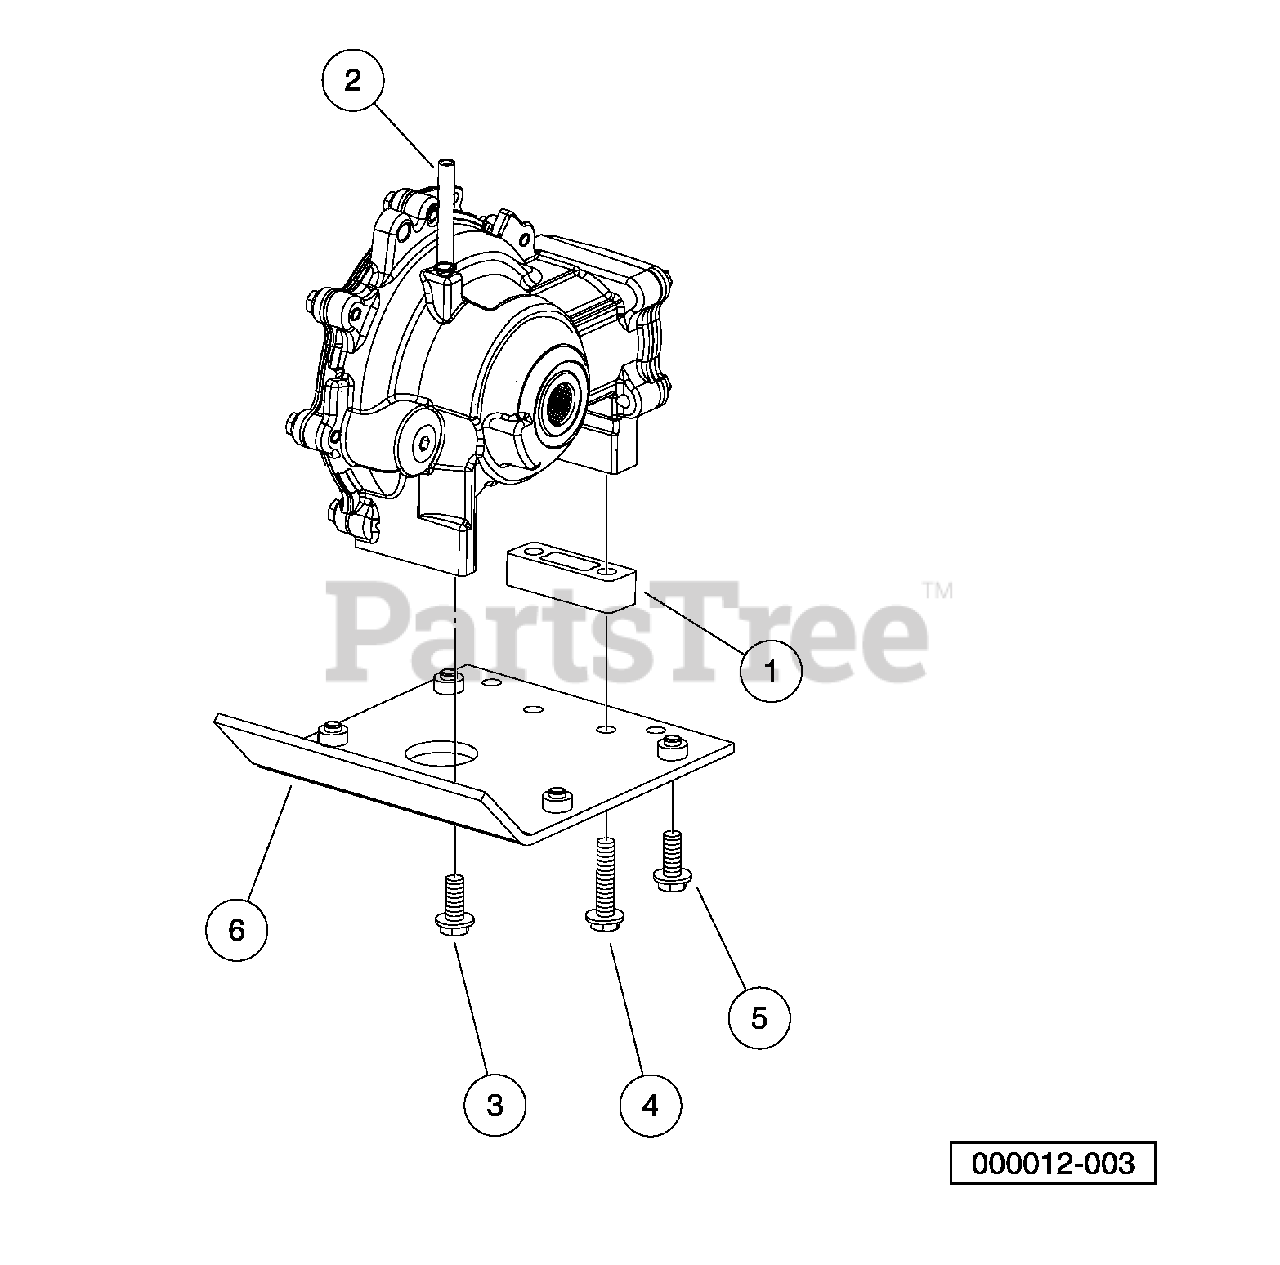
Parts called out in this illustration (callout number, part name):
1	Spacer Block, Diff
2	Hose, Vent, Front Diff
3	Bolt Flanged Head, 3/8-16x1.0 with Loctite
4	Bolt Flanged Head, 3/8-16x1.500 with Loctite
5	Bolt, Flange Head, M10 X 1.5 X 25
6	Asm, Mount, Diff Plate
